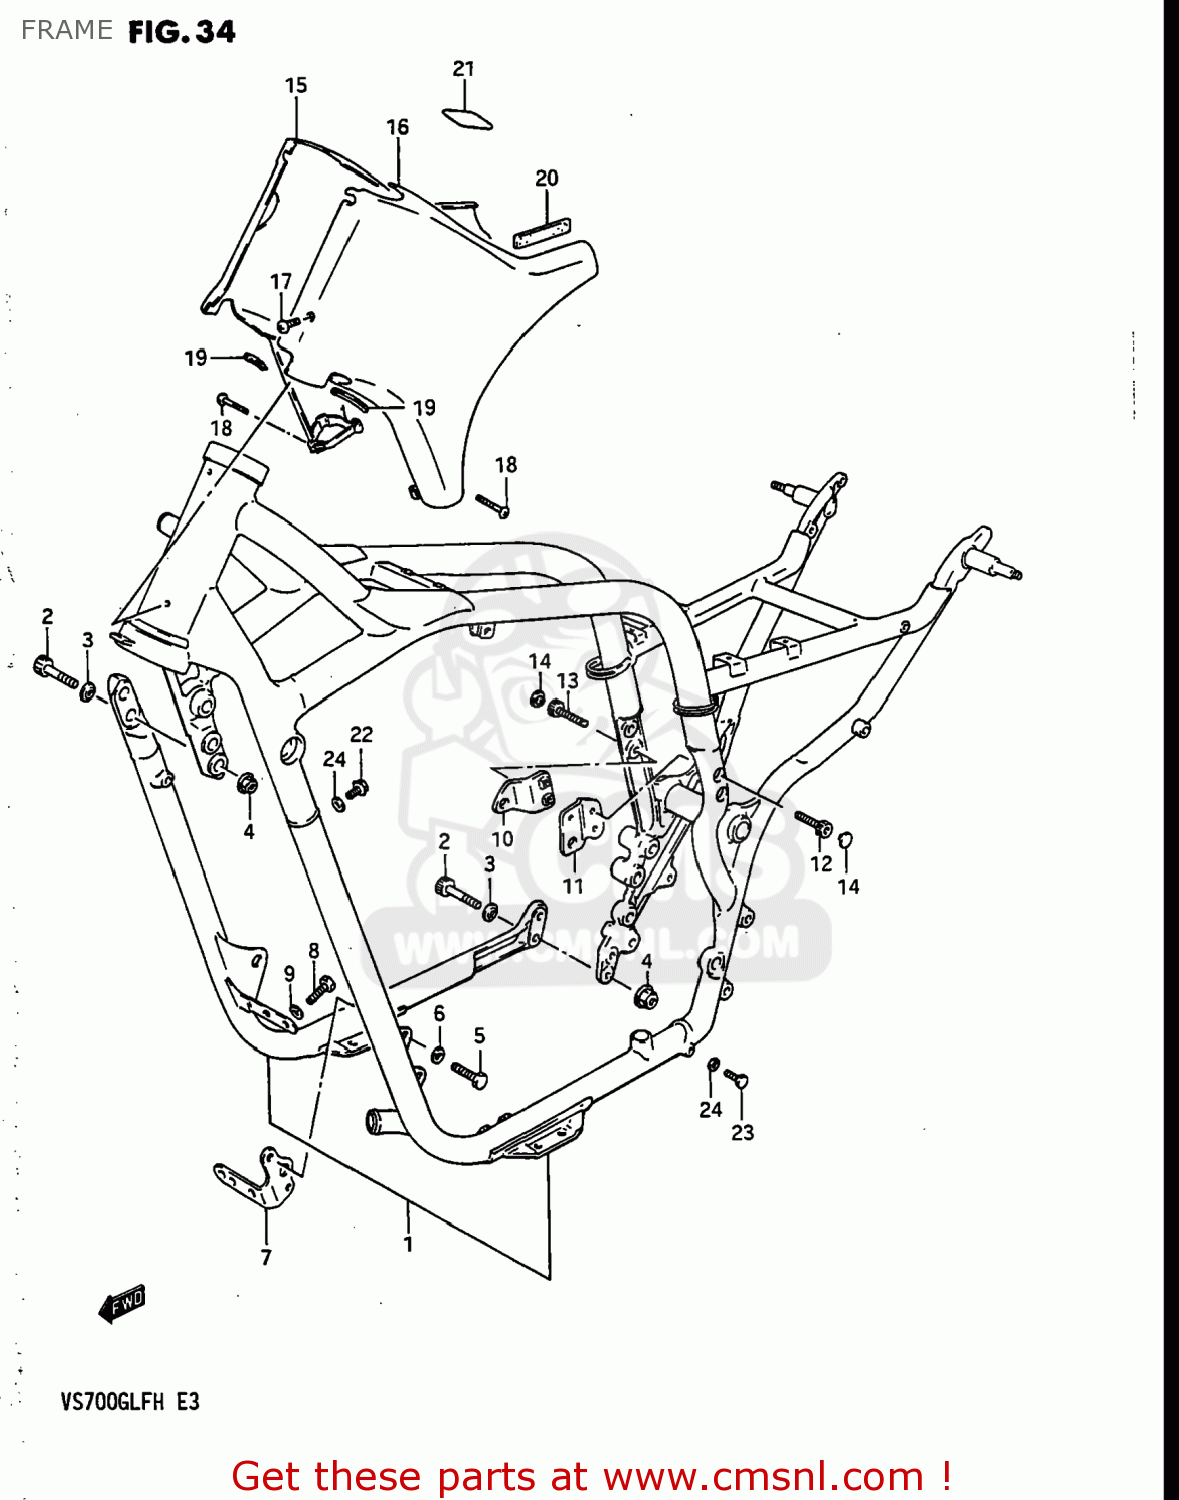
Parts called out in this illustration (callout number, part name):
1	FRAME
2	BOLT(10X33)
3	WASHER
4	NUT 10MM
5	BOLT
6	WASHER,LOCK,8.
7	PLATE,ENGINE MOUNTING
8	BOLT
9	WASHER,LOCK,8.
10	PLATE,ENGINE MOUNTING
11	PLATE,ENGINE MOUNTING
12	BOLT(8X30)
13	BOLT 8X30
14	CAP(OD:14.5)
15	COVER,FRAME HEAD,RIGHT
16	COVER,FRAME HEAD,LEFT
17	SCREW 5X10
18	SCREW
19	MOLDING,FUEL TANK
20	PROTECTOR(20X90)X2
21	TAPE,FRAME HEAD COVER
22	UNION
23	BOLT
24	GASKET(6.2X11X1).2 (NAS)
